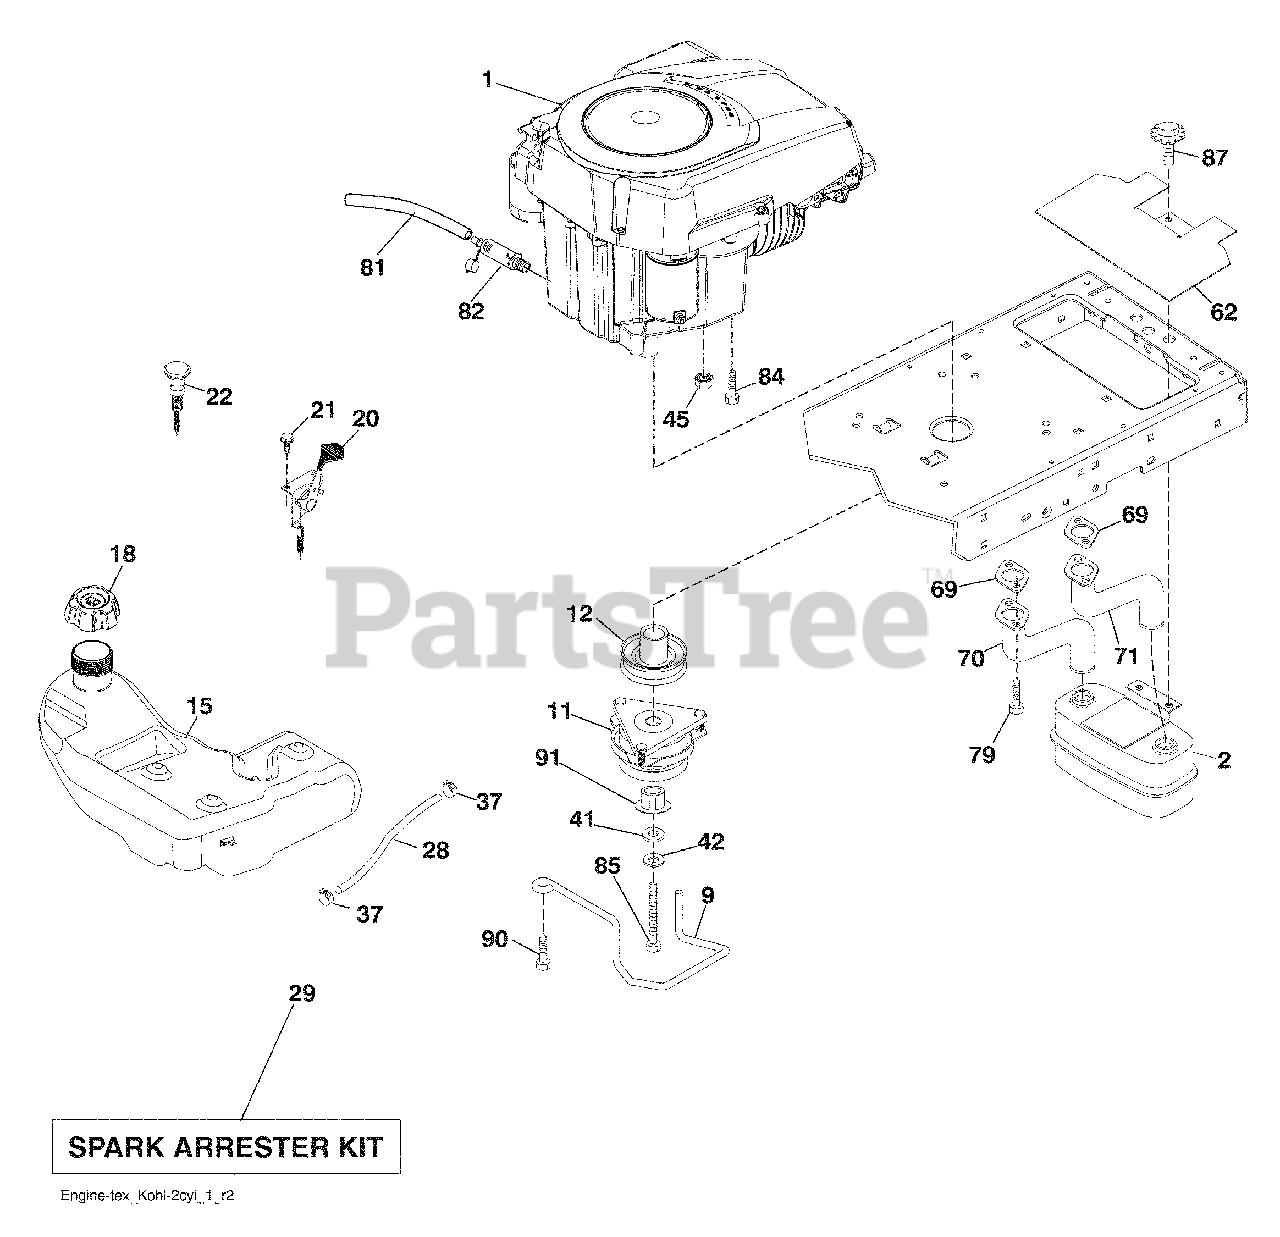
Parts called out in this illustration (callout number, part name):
9	Keeper Belt Engine
11	Clutch Electric
12	Pulley Engine
15	Tank Fuel 4.0
18	Cap Asm
20	Control Throttle
21	Screw #10 x 0.750 BOS Thread
22	Control Choke
28	Fuel Line
29	Spark Arrester Kit
37	Clamp Hose
41	Washer 1-1/2 OD x 15/32 ID x .250
42	Washer Lock 7/16
45	Nut Keps Hex 1/4-20 unc
62	Shield Heat Muffler
70	Tube Exhaust LH
71	Tube Exhaust RH
79	Screw Socket Head 5/16-18 x .75
81	Tube Drain Oil Easy
82	Plug Drain Oil
84	Screw 3/8-16 x 1
85	Bolt Hex 7/16-20 x 3.75 Gr. 5
87	Bolt 5/16-18 unc x 1 w/Sems
90	Screw 3/8-16 x 1
